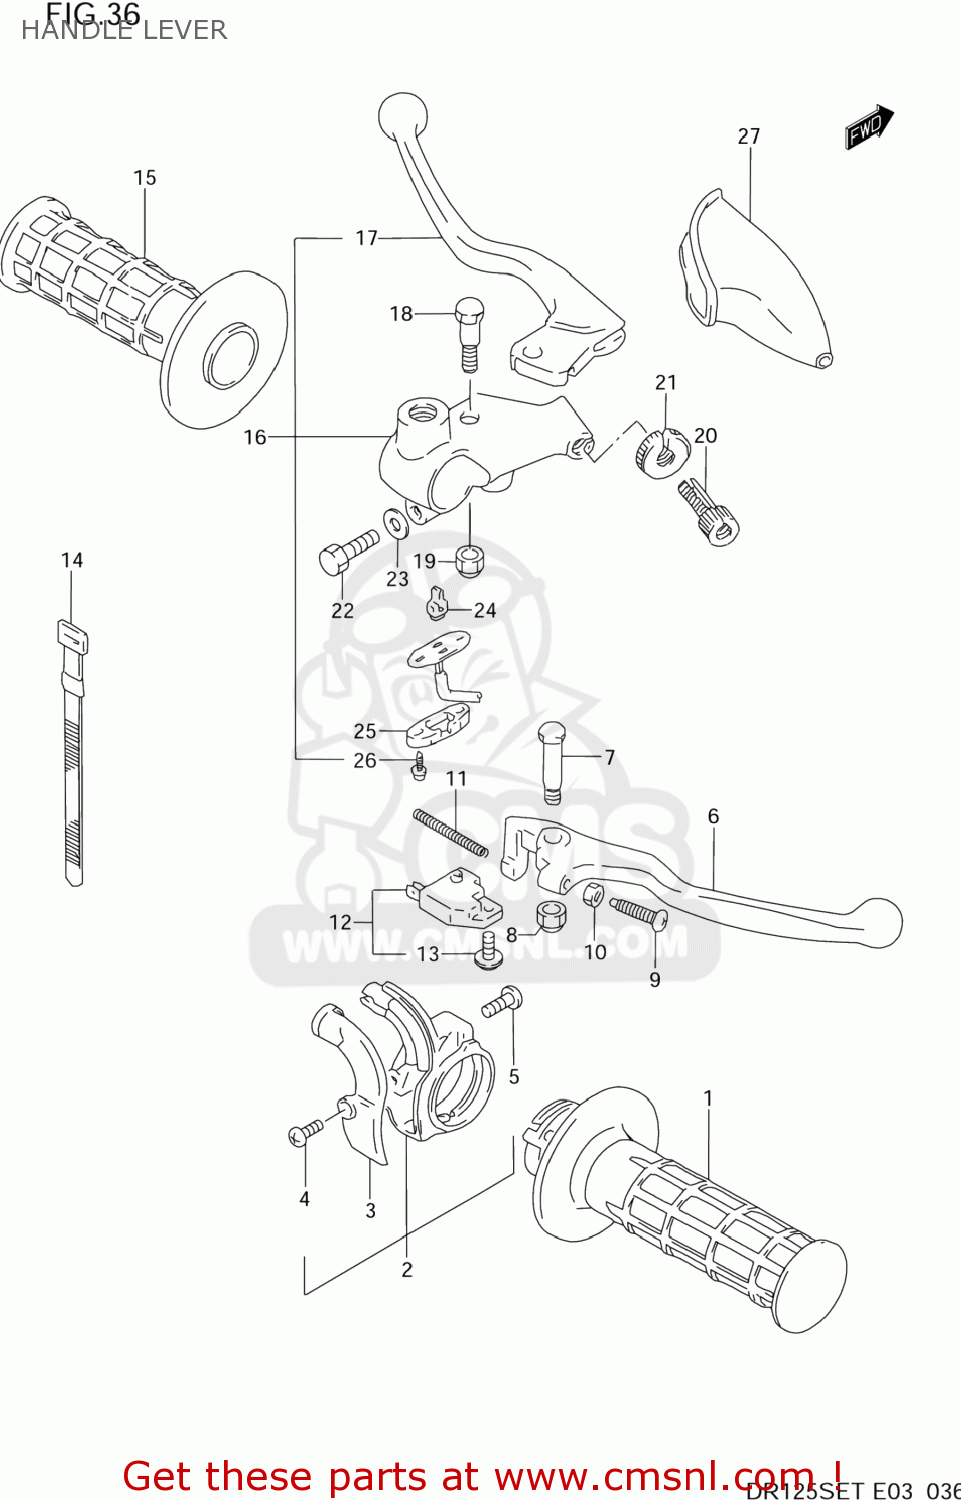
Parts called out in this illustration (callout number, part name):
1	GRIP,THROTTLE
2	CASE ASSEMBLY,THROTTLE
3	COVER,THROTTLE CASE
4	SCREW,UPPER
5	SCREW
6	LEVER,BRAKE
7	BOLT,BRAKE LEVER
8	NUT 6MM
9	BOLT,ADJUST
10	NUT
11	SPRING,RETURN
12	SWITCH ASSEMBLY,STOP
13	SCREW
14	CLAMP(L:120)
15	GRIP,L
16	LEVER ASSY,CLUTCH
17	LEVER,CLUTCH
18	BOLT,LEVER PIVOT
19	NUT 6MM
20	ADJUSTER,CABLE
21	NUT,LOCK
22	BOLT
23	WASHER
24	CONTACT,SWITCH
25	COVER,FR BK TERMINAL BASE
26	SCREW
27	COVER,CLUTCH LEVER
